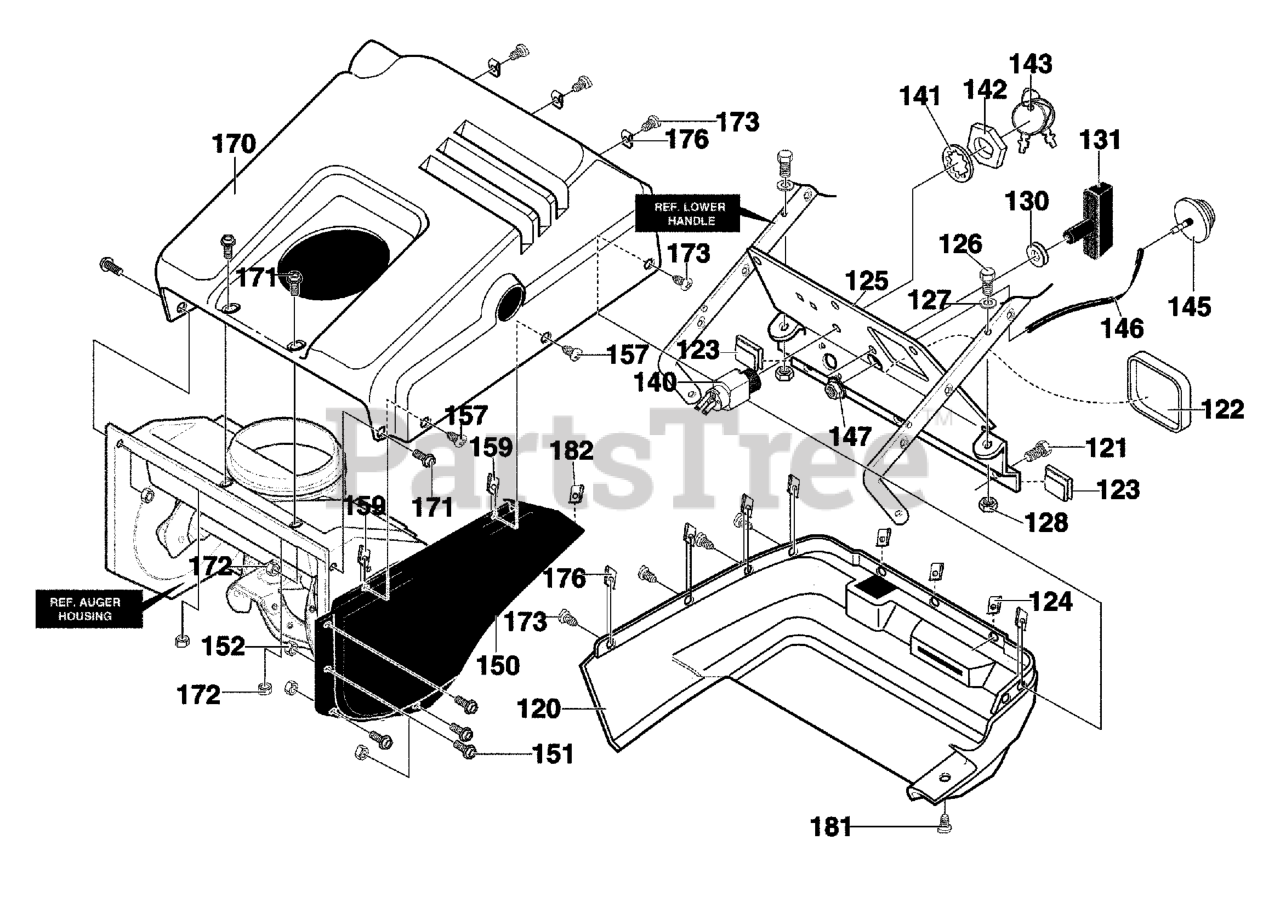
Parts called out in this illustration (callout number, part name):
120	COVER, BOTTOM
121	SCREW, 1/4-14X.75
122	PANEL, SPARK ACCESS
123	CLIP, S TINNERMAN
124	NUT, 1/4-10 SPEED J TYPE
125	CONTROL PANEL
126	SCREW, 1/4-20X1.25
127	FLATWASHER, .281X.63X.065
128	NUT, 1/4-20 REGHEXCTRLK
130	GOMMET & WASHER
131	KNOB T
140	SWITCH, IGNIT.
141	WASHER, REGINTLK .640X1.1X.05
142	NUT. 5/8-32
143	KEYS & RING
145	PRIMERBULB
146	HOSE PRIM 9.50LG
147	NUT, 1/4-20 REGHEXKEPS
150	COVER, BELT
151	SCREW, 10-24X.50
152	NUT, #10-24 REGHEXCTRLK
157	SCREW, 1/4-14X.75
159	NUT, 1/4-10 SPEED J TYPE
170	COVER, TOP
171	SCREW,#10-24X.50
172	NUT #10-24 REGHEXCTRLK
173	SCREW, 1/4-14X.75
176	NUT, 1/4-10 SPEED J TYPE
181	SCREW, 1/4-14X.75
182	NUT 1/4-10 SPEED J TYPE
